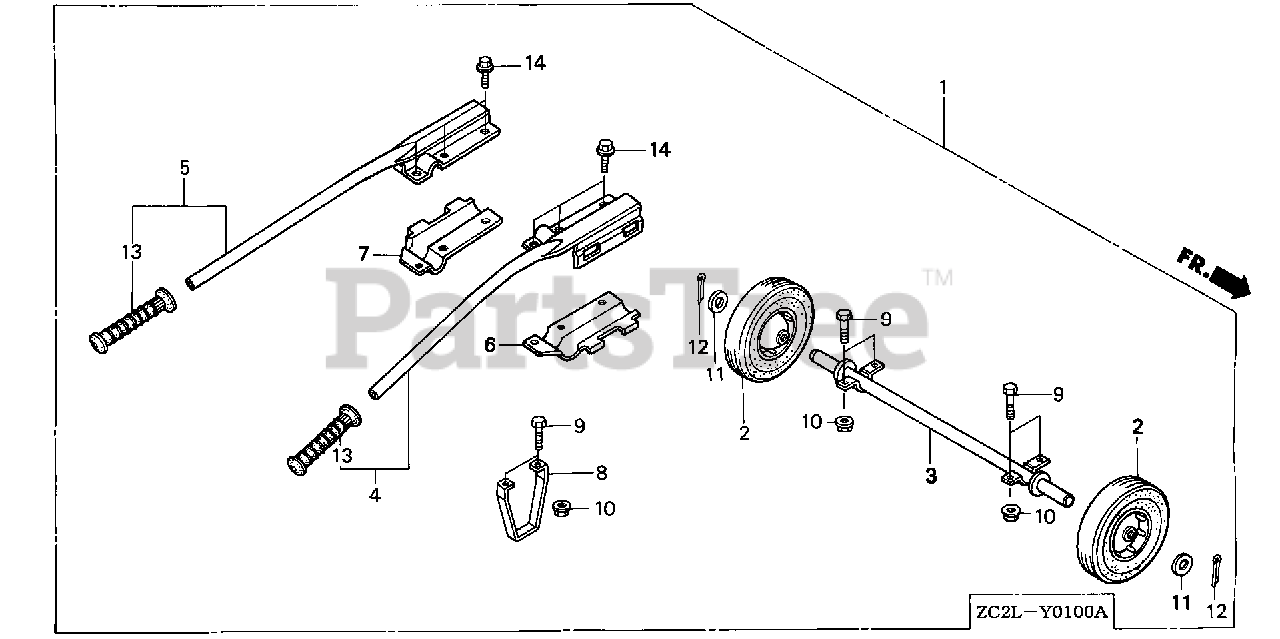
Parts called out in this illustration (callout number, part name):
1	WHEEL KIT (2-WHEELS)
2	WHEEL (GLEASON 10"X2.75"=254X70)
3	SHAFT, WHEEL
4	HANDLE, R. (LOWER)
5	HANDLE, L. (LOWER)
6	BRACKET, R. HANDLE (UPPER)
7	BRACKET, L. HANDLE (UPPER)
8	STAND
9	BOLT, HEX. (8X16)
10	NUT, FLANGE (8MM)
11	WASHER, PLAIN (20MM)
12	PIN, SPLIT (4.0X28)
12	PIN, SPLIT (4.0X30)
13	GRIP D, R. HANDLE
14	BOLT, FLANGE (8X16)
